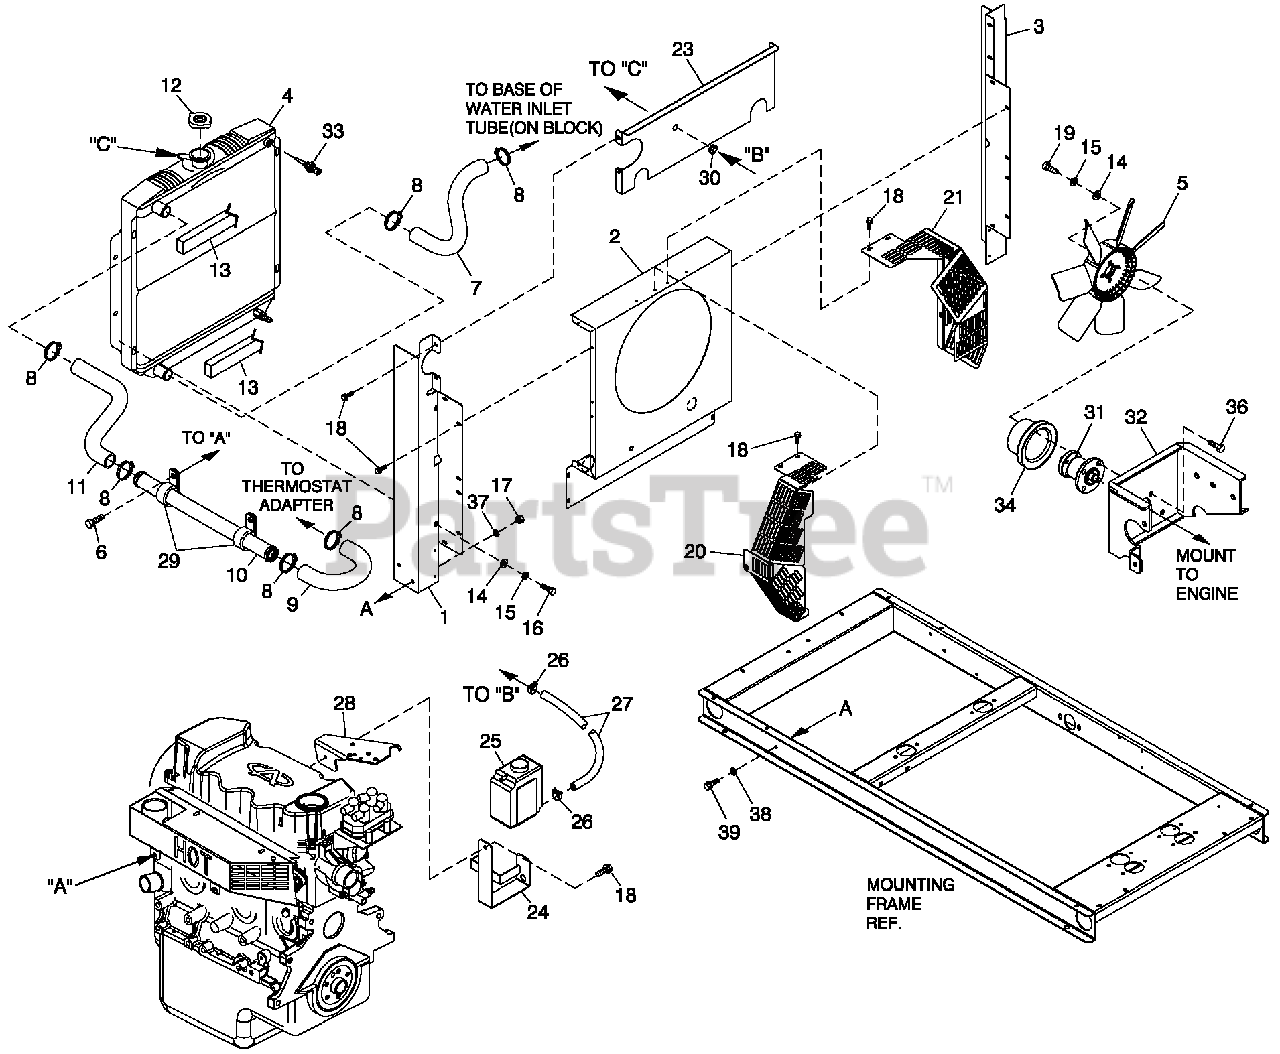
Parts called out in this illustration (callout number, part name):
1	RADIATOR SUPPORT LH SIDE 1.6L
2	VENTURI 1.6L
3	RADIATOR SUPPORT RH SIDE 1.6L
4	RADIATOR 1.6L CHY
5	FAN COOL 450MM DIA 7 BLADE
6	SCREW HWHTF M6-1.0 X 16
7	HOSE LOWER RADIATOR 1.6L
8	CLAMP HOSE #24 B1.06-2.00
9	HOSE REAR COOLANT 1.6L
10	TUBE ENGINE COOLANT 1.6L
11	HOSE UPPER RADIATOR 1.6L
12	CAP RADIATOR
13	TAPE FOAM 1 X 1 (24" LG)
14	WASHER FLAT 1/4-M6 ZINC
15	WASHER LOCK M6-1/4
16	SCREW HHFC M6-1.0 X 20 G8.8
17	NUT HEX M 8-1.25 G8 CLEAR ZINC
18	SCREW THF M6-1 X 12 N WA Z/JS
19	SCREW HHC M6-1.0 X 20 G8.8
20	GUARD FAN LH C1
21	GUARD FAN RH C1
23	RADIATOR BLOCK-OFF
24	BRACKET COOLANT TANK
25	TANK COOLANT RECOVERY
26	CLAMP HOSE BAND 1/4
27	HOSE 9/32 ID (43" LG)
28	BRACKET STEPPER MOTOR COOLANT
29	CLAMP VINYL 1.31 X .281 Z
30	GROMMET 5/8"X 1 1/8"X 5/16"
31	ASSY FAN BEARING SUPPORT
32	BRACKET FAN ALT ADAPTER 1.6L
33	PROBE COOLANT LEVEL 3/8 NPTF
34	PULLEY - FAN 95 DIA
35	TIE WRAP UL 7.4" X .19" BLK
36	SCREW HHC M8-1.25 X 16 G8.8
37	WASHER SHAKEPROOF EXT 5/16 STL
38	WASHER LOCK M8-5/16
39	SCREW HHC M8-1.25 X 20 G8.8
